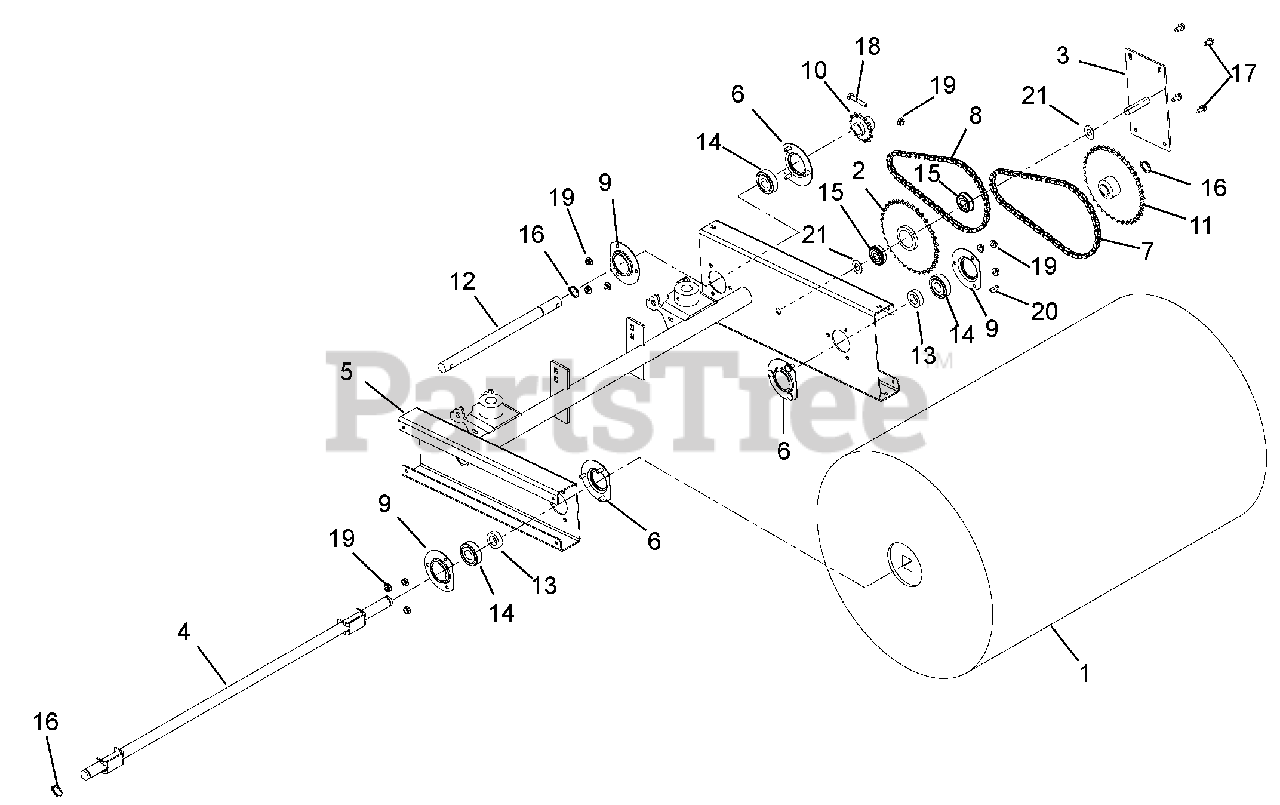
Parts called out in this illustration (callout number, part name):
1	BRUSH, 18"DIA X 28"WIDE
2	SPROCKET, REDUCTION IDLER
3	PLATE, IDLER REDUCTION MOUNT
4	SHAFT, 28" BRUSH
5	FRAME, POWER BROOM
6	BEARING FLANGE
7	CHAIN, #40-54 LINKS
8	CHAIN, #41-50 LINKS
9	BEARING FLANGE
10	SPROCKET, DRIVE
11	SPROCKET, DRIVEN
12	SHAFT, TRANSMISSION
13	SPACER .755X1.250X.370
14	BRG-BALL .750X1.750X.50
15	BRG-BALL .50X1.38X.438 SEALED
16	RG-RTNG-EXT .689X.078
17	SCR-TAP .25-20X.50 HWH TR YWZ
18	@BLT-HEX .25-20X1.75 GR5 YWZC
19	@NUT-LK-TOP-FLG .25-20 YWZC
20	KEY-WDRF .188X.75X.313 SAE 9
21	@WSHR-FL-STL.563X1.38X.109YWZC
